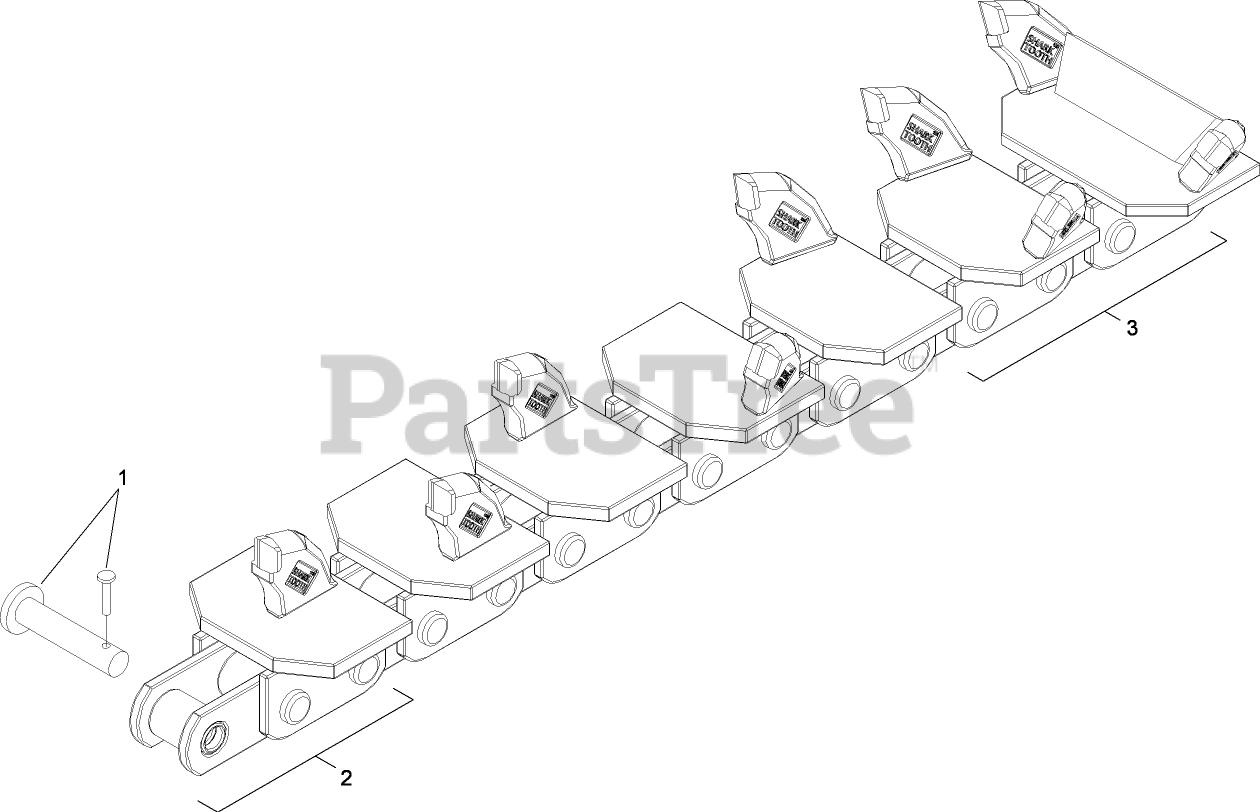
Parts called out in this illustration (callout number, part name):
1	PIN AND KEY KIT
2	STATION-REPAIR, SINGLE
3	STATION-REPAIR, 6 INCH
